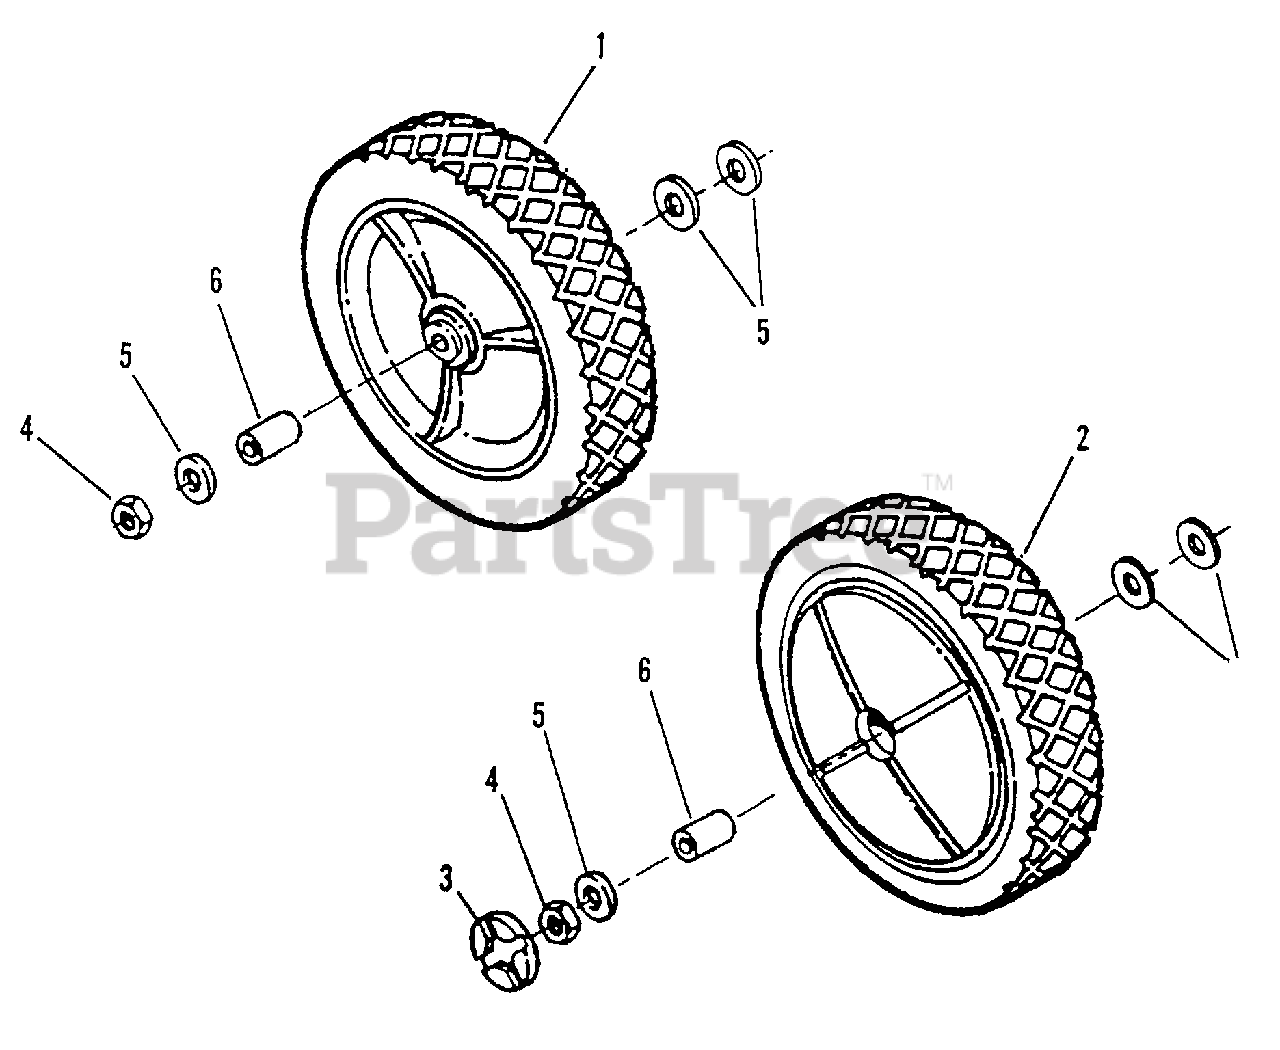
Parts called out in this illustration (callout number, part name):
1	WHEEL, 8 x 1.75 Plastic (Push)
2	WHEEL, 8 x 1.75 Plastic (Self-Prop)
3	PLUG, Wheel
4	NUT, 7/16-20 Hex (Thin)
5	WASHER, 7/16 x 1" O.D. Flat
6	BUSHING, Axle
